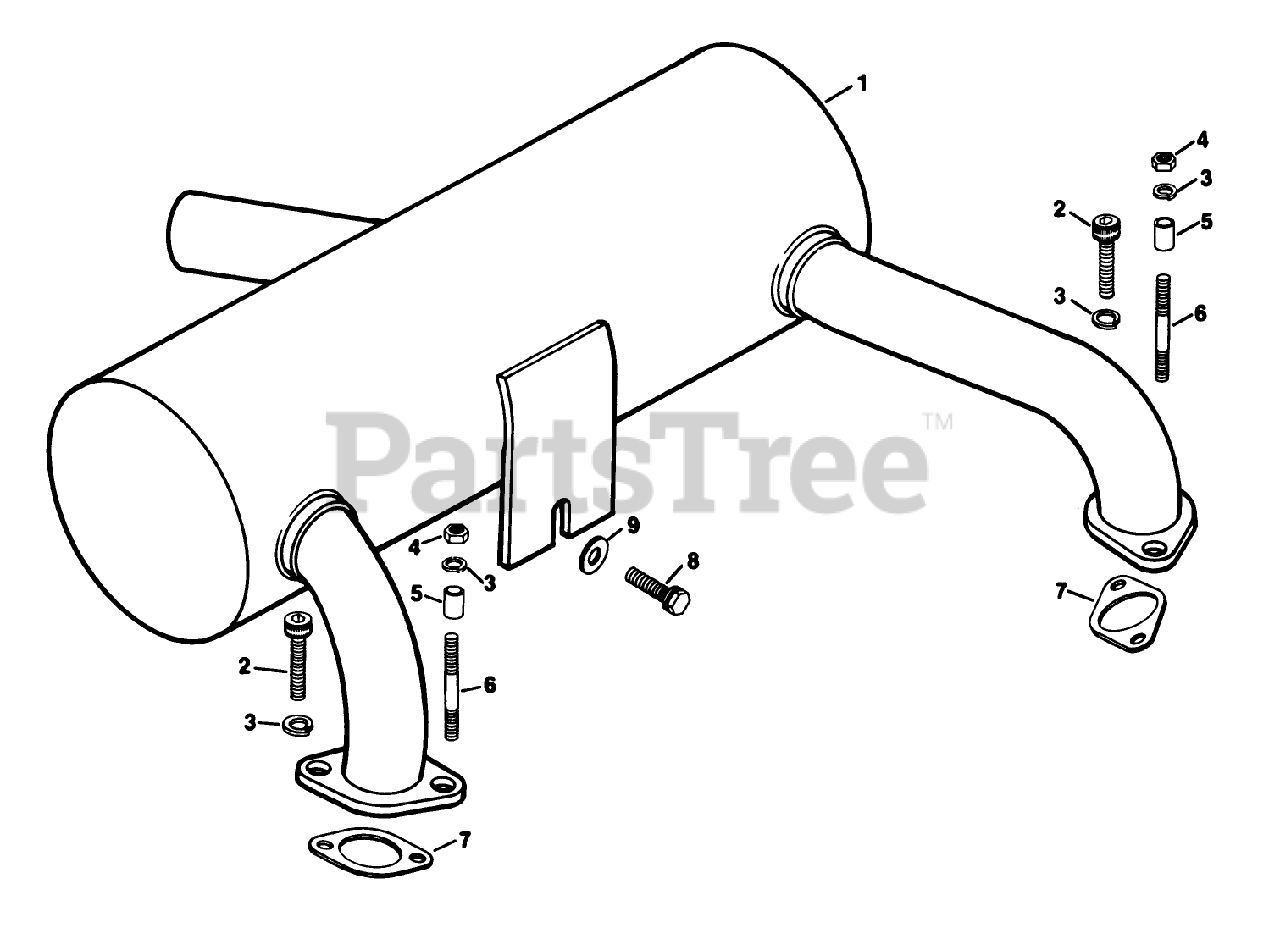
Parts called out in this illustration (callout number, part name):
1	Muffler
2	Screw
3	Washer
7	Gasket Exhaust
8	Screw
9	Washer
